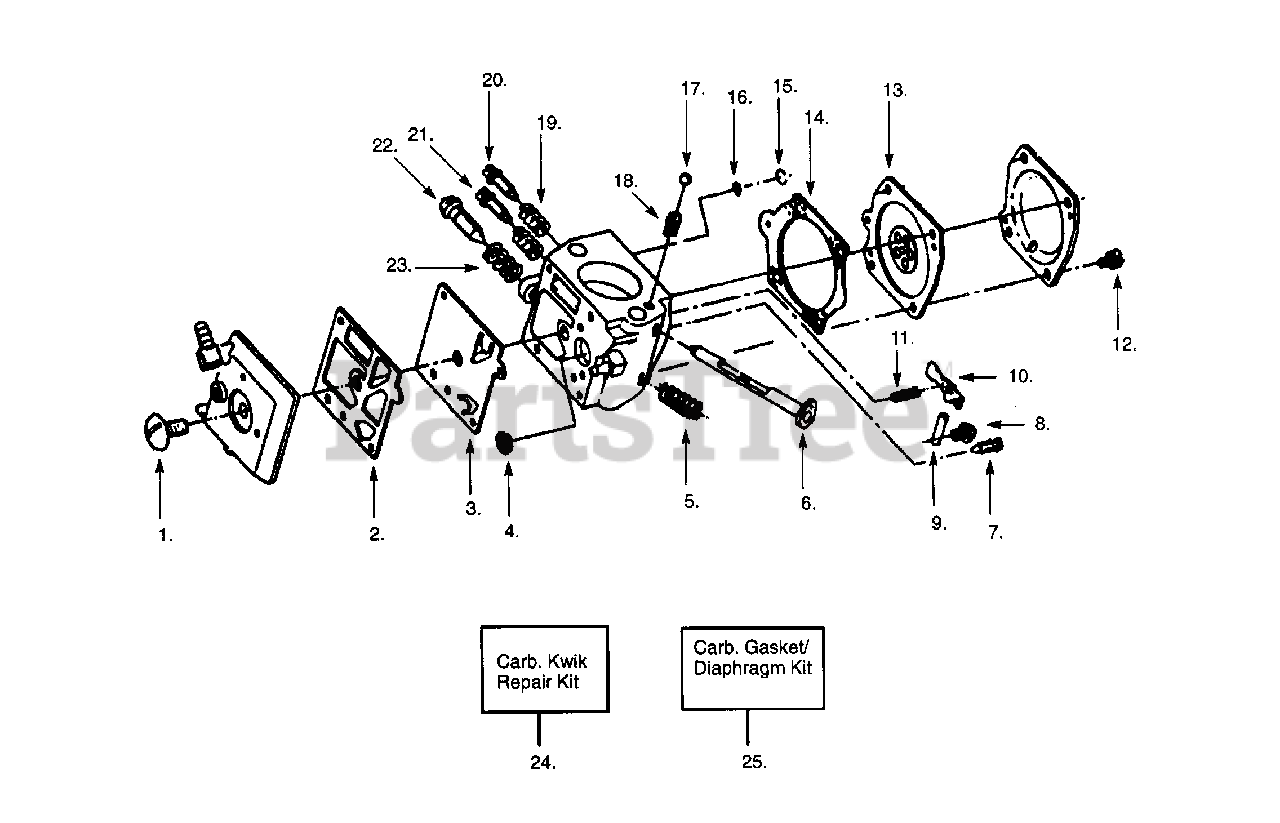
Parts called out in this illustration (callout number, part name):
2	Fuel Pump Gasket
3	Fuel Pump Diaphragm
4	Inlet Screen
5	Throttle Spring
6	Choke Shaft & Lever Ass'y.
7	Inlet Needle Valve
9	Pin
10	Metering Lever
13	Metering Diaphragm
14	Metering Diaphragm Gasket
15	Retaining Ring
16	Check Valve Screen
18	Spring
19	Needle Adjusting Spring
20	High Speed Needle
21	Idle Needle
22	Idle Adjust Screw
23	Idle Adjust Spring
24	Kwik Repair Kit (Inc. 2,3,4,7,8,9,10,11, 13,14,15,16,26,27)
25	Carb. Gasket Kit
26	Welch Plug
27	Plug Cup
